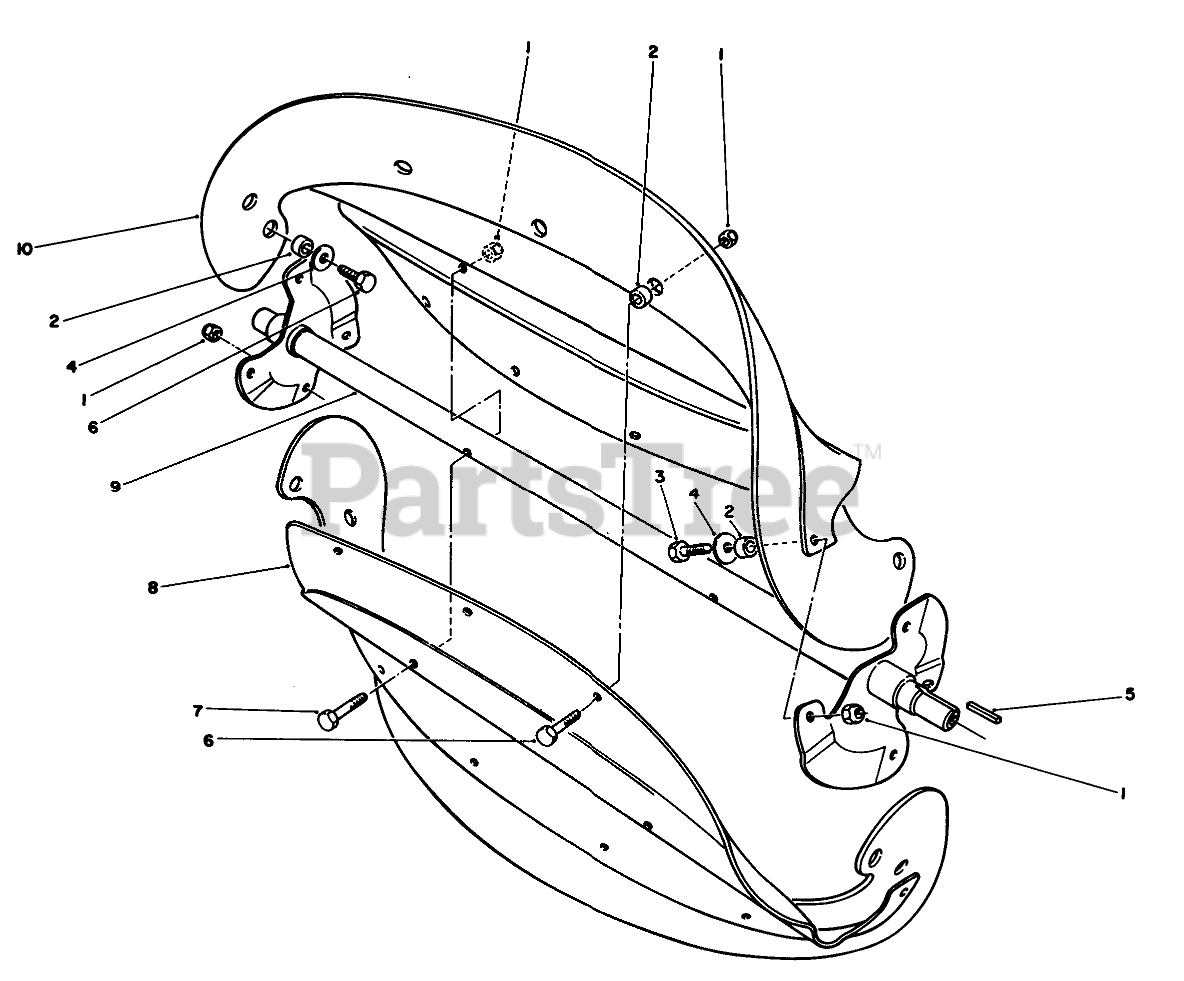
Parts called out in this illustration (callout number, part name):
1	NUT-LOCK, NI
2	SPACER-BLADE, ROTOR
3	SCREW-HH
4	WASHER-FLAT
5	KEY-SQUARE
6	SCREW-HH
7	SCREW-HH
8	ROTOR
9	Rotor Shaft Assembly
10	Blade-Rotor
